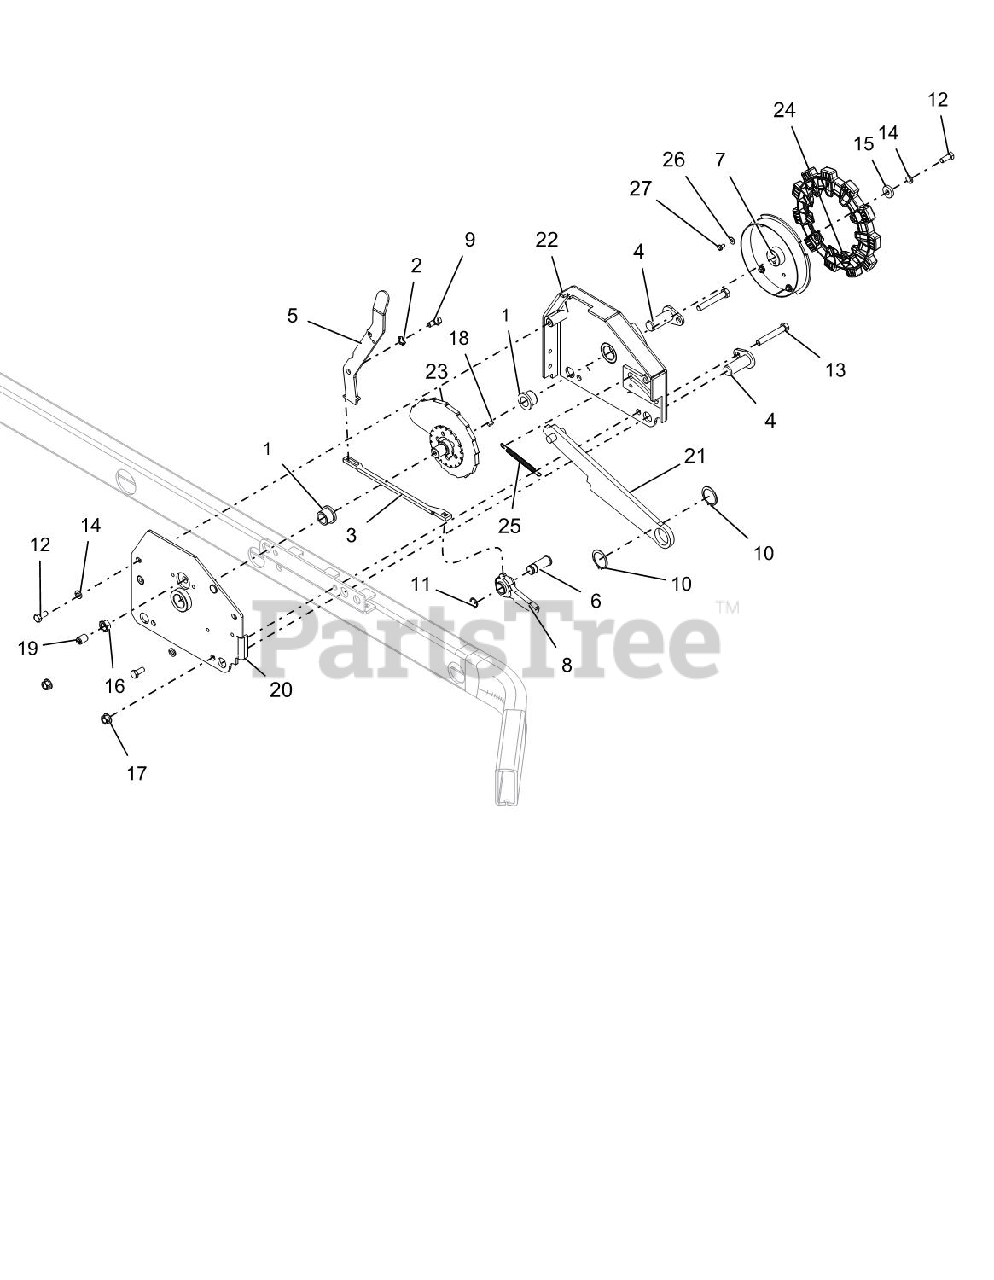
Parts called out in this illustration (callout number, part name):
1	BUSHING, FLANGE
2	WAVE WASHER .390X.655X.110
3	LINK, TRANSPORT LOCK
4	WLDMT, PIN
5	LEVER, TRANSPORT LOCK-BLACK
6	PIN, CLEVIS .625 SNAP RING
7	WLDMT, HOC WHEEL (RED)
8	WLDMT, LOCK PAWL
9	BOLT, SHLDR .38-16 x .437 HEX YZ
10	RG-RTNG-EXT 1.25x.050
11	RG-RTNG-EXT .625x.050
12	BLT-HEX .31-18X.75 GR5 YWZC
13	BLT-HEX .38-16X2.50 GR5 YWZC
14	WSHR-LK .31X.078 REG YWZC
15	WSHR-FL-STL .328X.87X.179 YWZC
16	NUT, JAM .500-13 YWZC
17	NUT, LK-CTR-FLG .38-16 YWZC
18	KEY-SQ .188X.188X.375
19	BALL SPRING PLUNGER, .500-13
20	WLDMT, HOC OUTER-RED
21	WLDMT, HOC LINK-BLACK
22	WLDMT, HOC INNER-RED
23	WLDMT, CAM HOC
24	WHEEL, HOC
25	SPRG, EXTENSION
26	WSHR-FL-STL.219X.500X.049YWZC
27	SCR, TAP 10-24X.375 PRE-COAT 80
